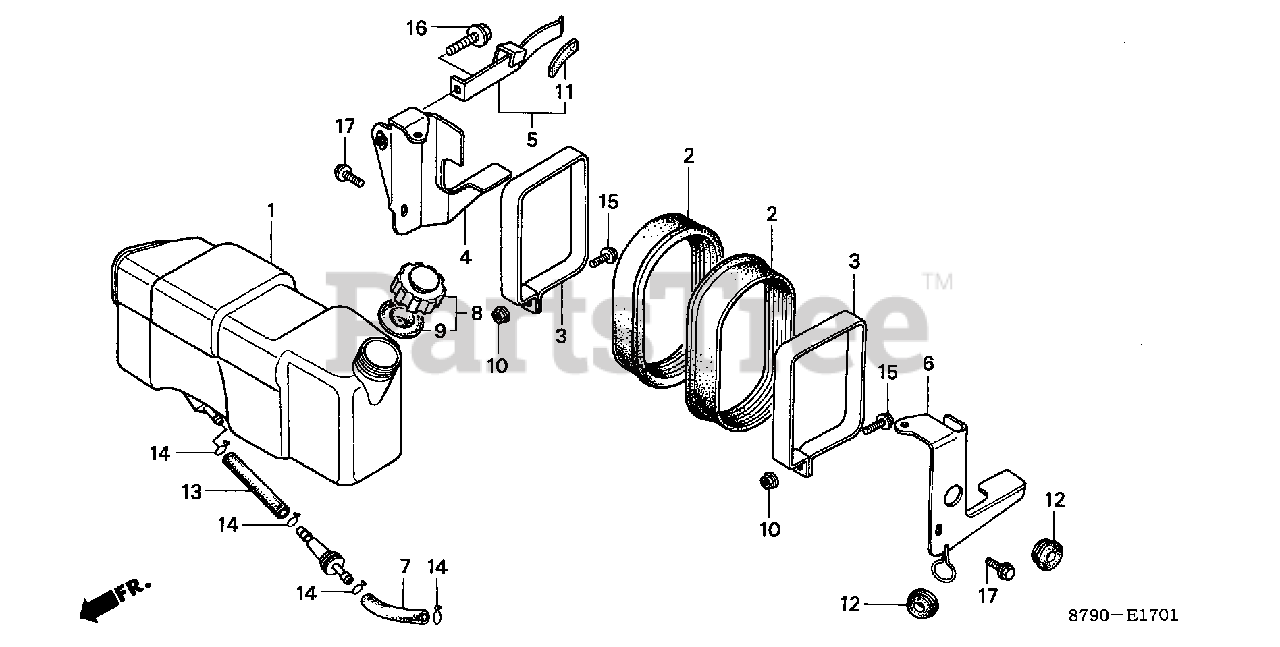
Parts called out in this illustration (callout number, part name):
1	TANK, FUEL
2	RUBBER, TANK SEAT
3	BAND, FUEL TANK
4	STAY A, TANK
5	PLATE ASSY., TANK SET
6	STAY B, TANK
7	TUBE, FUEL
8	CAP ASSY., FUEL (NOT AVAILABLE)
9	GASKET, FUEL CAP
10	NUT, FLANGE (6MM)
11	CUSHION, HOOD (NOT AVAILABLE)
12	GROMMET, BREATHER PIPE (NOT AVAILABLE)
13	BULK HOSE, FUEL (5.5X3000) (5.3X55)
14	CLIP, TUBE (B10)
15	BOLT, FLANGE (6X12)
16	BOLT, FLANGE (6X14)
17	BOLT, FLANGE (6X18)
